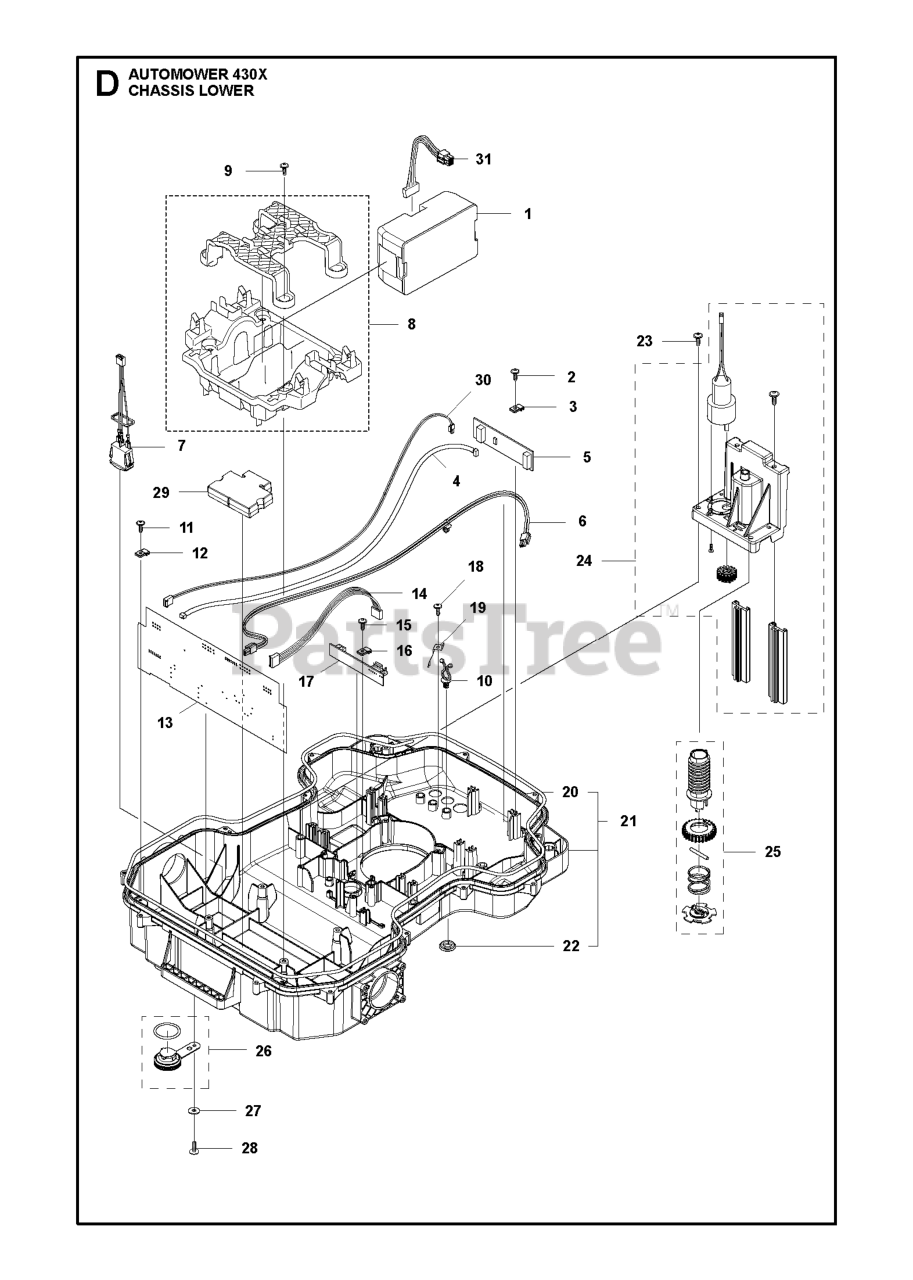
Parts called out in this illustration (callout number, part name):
1	BATTERY
2	SCREW 14MM
3	CLAMP PCB
4	LOOM LOOP SENSOR
5	PRINTED CIRCUIT ASSY LOOP SENS
6	LOOM CHARGING LINK HIGH CHARGI
7	LOOM ON/ OFF
8	HOLDER KIT BATTERY
9	SCREW ITXPANT
10	HOLDER TWIST LOCK
11	SCREW 14MM
12	CLAMP PCB
13	PRINTED CIRCUIT ASSY PCBA MAIN
14	LOOM HEIGHT ADJUSTMENT
15	SCREW 14MM
16	CLAMP PCB
17	PRINTED CIRCUIT ASSY PCBA CUTT
18	SCREW 14MM
19	SPRING GUIDE HEIGHT ADJUSTMENT
20	SEALING STRIP
21	CHASSIS KIT LOWER
22	GROMMET M16
23	SCREW 14MM
24	MOTOR ASSY HEIGHT MOTOR
25	SCREW KIT
26	PLUG KIT
27	WASHER
28	SCREW ITXPANT
29	WEIGHT CENTER
30	WIRING ASSY LED LIGHT EXTENSIO
31	WIRING ASSY BATTERY CABLE
